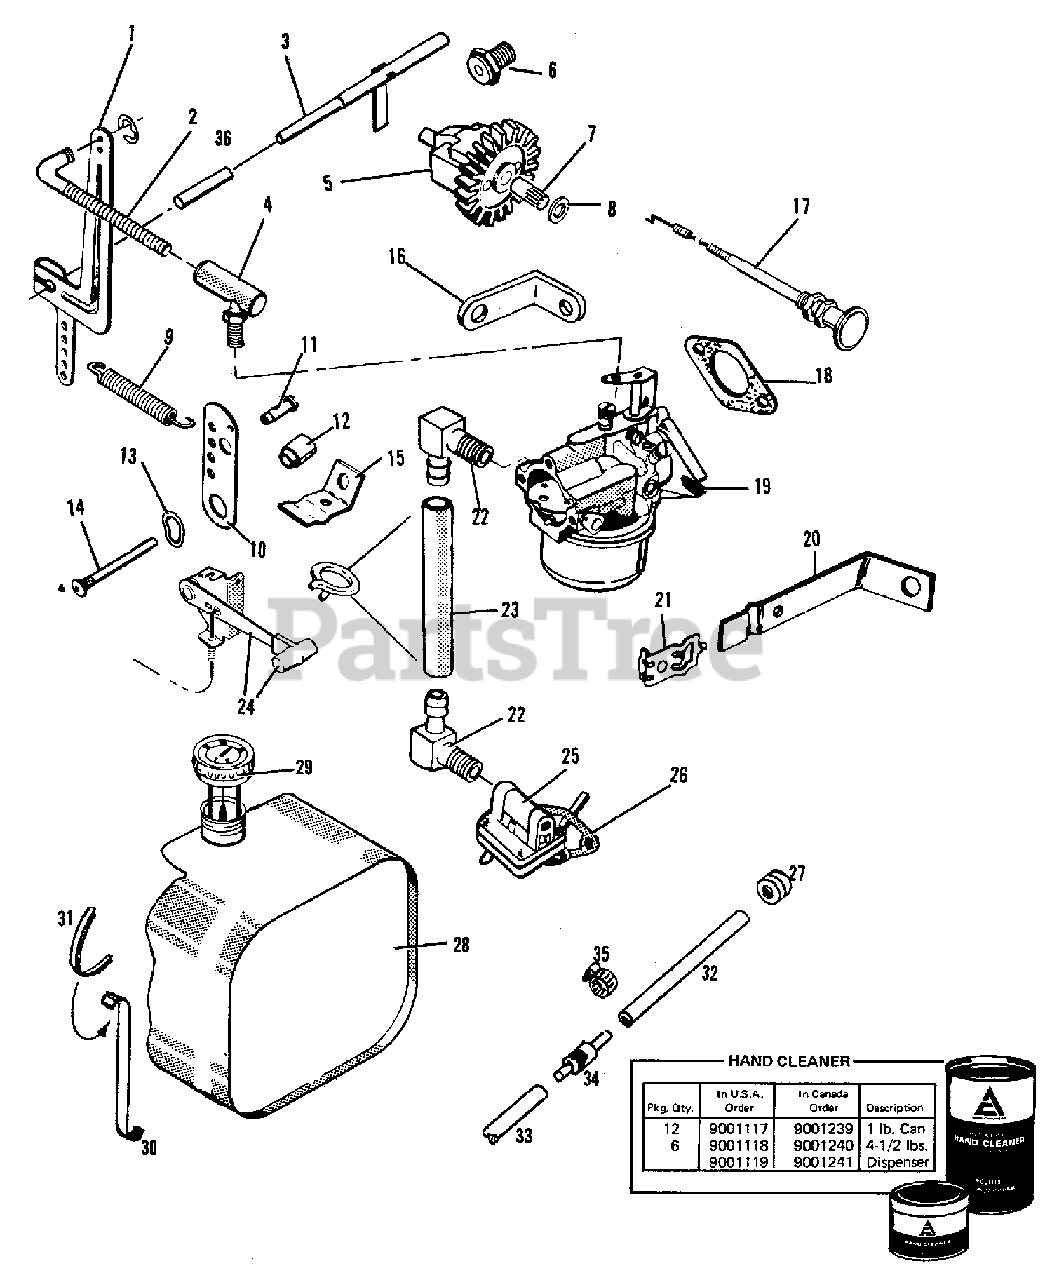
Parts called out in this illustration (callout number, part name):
1	LEVER, Governor (10 & 14 HP)
1	LEVER, Governor (16 HP)
1	SCREW, 1/4NC x 1-1/4
1	NUT, 1/4NC
2	ROD, Throttle
2	RETAINER, Rod
3	SHAFT ASSEMBLY, Governor Cross
4	JOINT ASSEMBLY, Ball
4	LOCKWASHER, #10
4	NUT, #10NF
5	GEAR ASSEMBLY
7	SHAFT, Governor
8	WASHER, Thrust
9	SPRING, Governor
10	BRACKET, Speed Control
11	PIN, Wire Swivel
11	SCREW, 1/4NC x 1/4
11	LOCKWASHER, 1/4
13	WASHER, Tension
14	PIN, Governor Stop
15	BRACKET, Throttle (10 & 14 HP)
15	BRACKET, Throttle (16 HP)
15	SCREW, #10NC x 3/8
15	LOCKWASHER, #10 Intermediate Tooth
16	BRACKET, Adjusting Screw
17	CHOKE ASSEMBLY, Carburetor Air
18	GASKET, Carburetor (Included In Engine Gasket Set)
19	CARBURETOR ASSEMBLY (10 HP)
19	CARBURETOR ASSEMBLY (14 HP)
19	CARBURETOR ASSEMBLY (16 HP)
19	WASHER, 1/4 (Carburator Baffle To Cylinder Head)
19	REPAIR KIT, Carburetor
20	BRACKET, Choke
21	CLIP, Choke Cable (Except 14 H.P.)
22	ELBOW, Hose
23	HOSE, Fuel (Pump To Carburetor)
23	CLAMP, Hose, 7/16 to 35/32
24	LEVER ASSEMBLY, Throttle Control
24	KNOB, Handle
25	PUMP ASSEMBLY, Fuel
26	GASKET, Fuel Pump (Included In Engine Gasket Set)
27	GROMMET, Rubber
28	TANK, Fuel
29	CAP, Fuel Tank
30	STRAP, Lower Tank
31	STRAP, Rubber
32	HOSE, 6" Fuel
33	HOSE, 11" Fuel
34	FILTER, Fuel
35	CLAMP, Hose, 11/16 to 1-1/4
